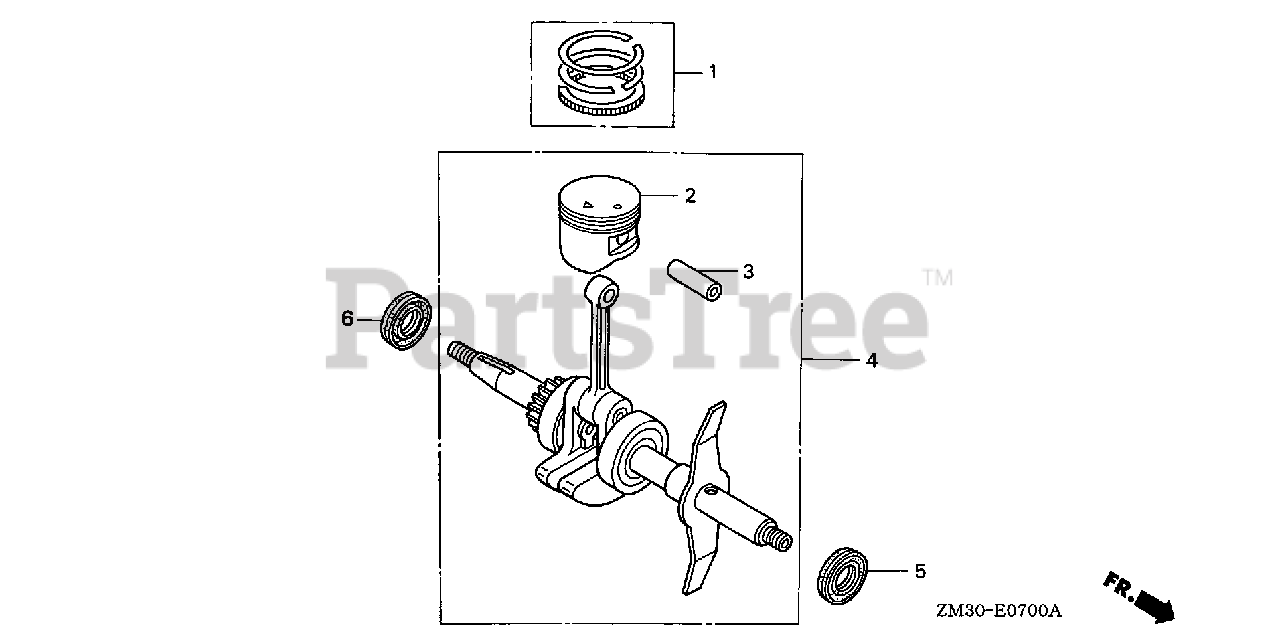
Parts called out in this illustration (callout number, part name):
1	RING SET, PISTON
3	PIN, PISTON
4	CRANKSHAFT
5	OIL SEAL (12X25X6)
6	OIL SEAL (15X25X6)
